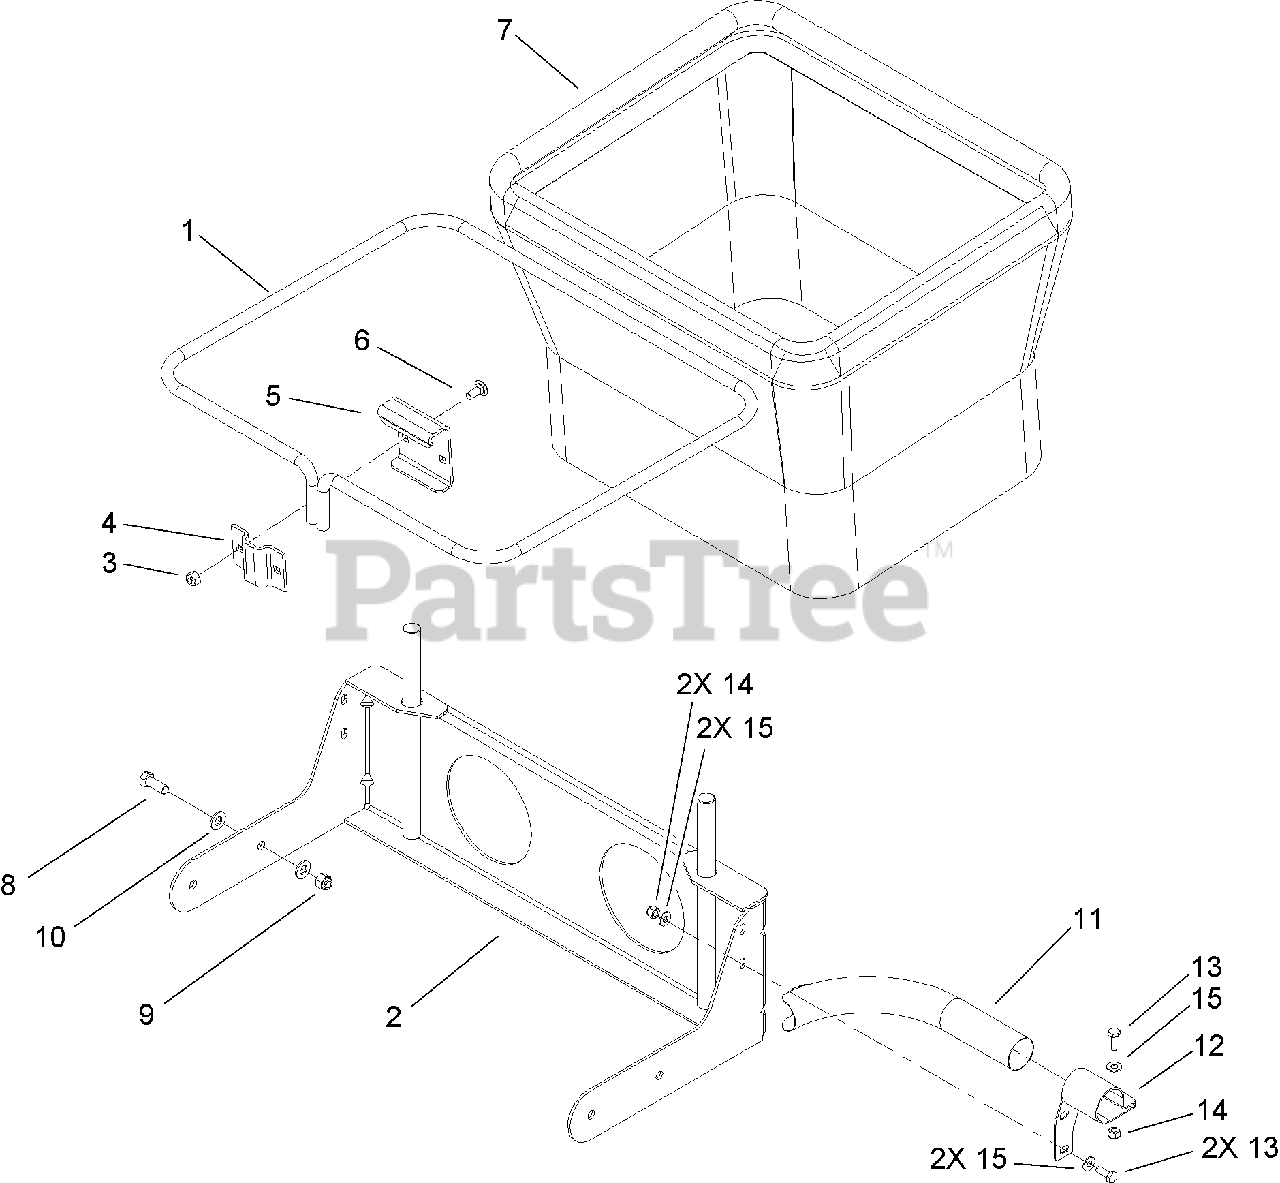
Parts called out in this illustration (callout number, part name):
1	FRAME-BAG
2	BAGGER SUPPORT ASM
3	NUT-LOCK, NI
5	HANGER-BAG
6	BOLT-CARR
8	SCREW-HH
9	NUT-LOCK, NI
10	WASHER-FLAT
11	EXHAUST PIPE ASM
12	BRACKET-EXHAUST
13	SCREW-HH
14	NUT-LOCK, NI
15	WASHER-FLAT
